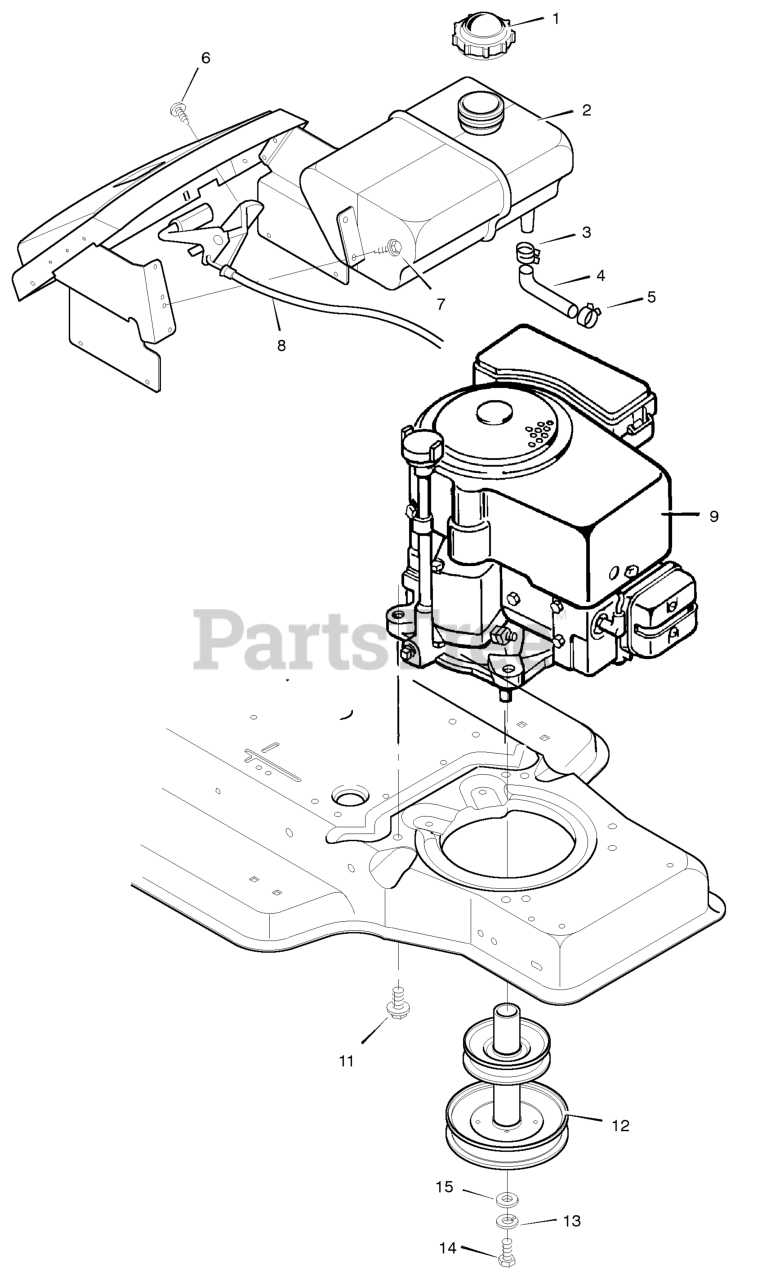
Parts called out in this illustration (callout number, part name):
1	Fuel Cap
2	Fuel Tank
3	Hose Clamp
4	Fuel Line
5	Hose Clamp
8	Throttle Control
9	Engine *
11	Bolt, Engine Mount
12	Stack Pulley Assembly
13	Lockwasher
14	Bolt, Hex
